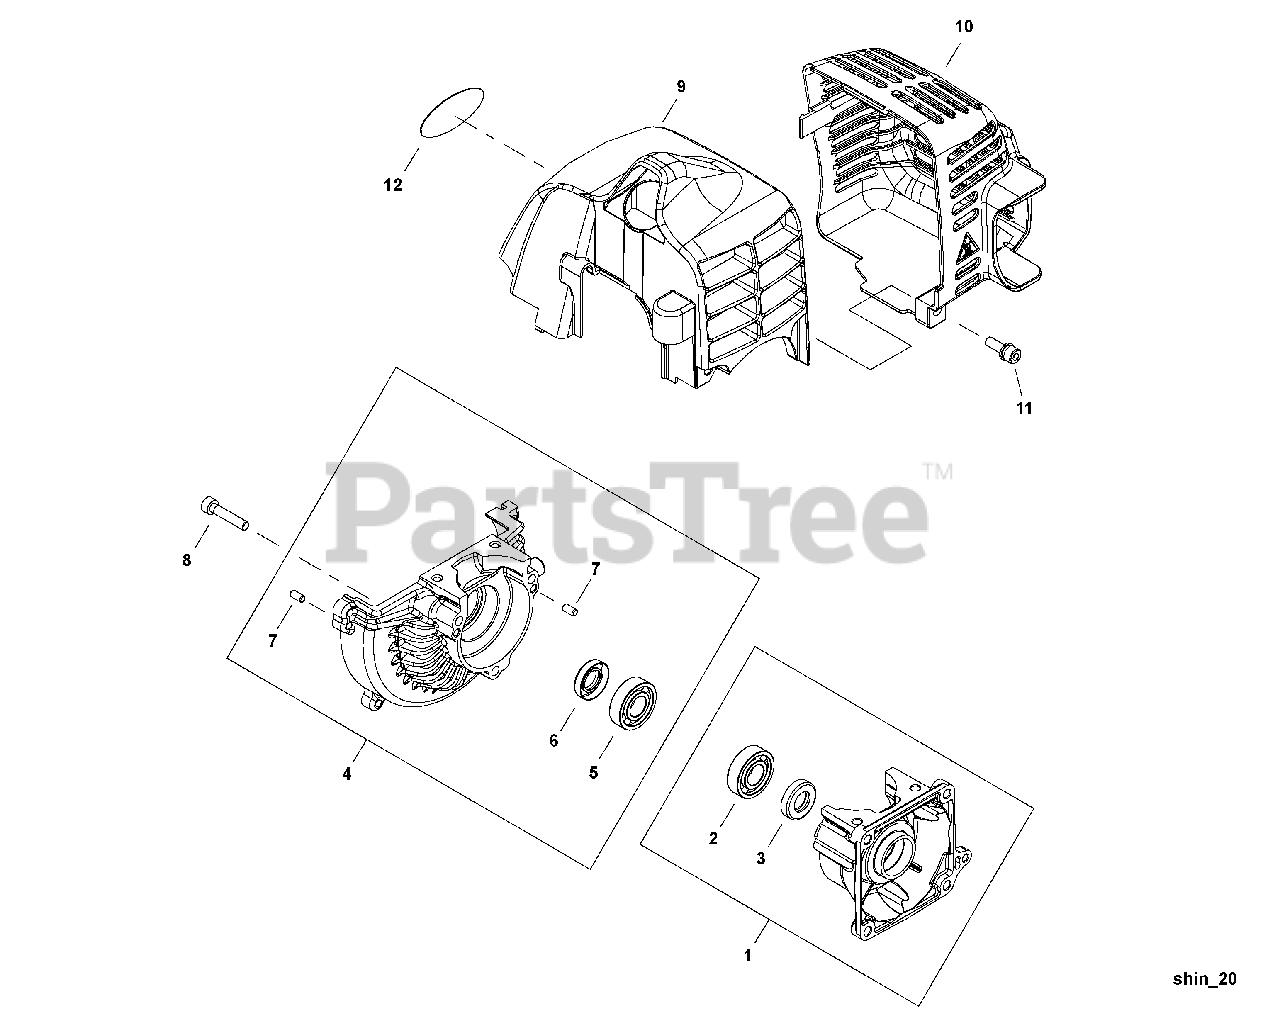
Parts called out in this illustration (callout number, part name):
1	CRANKCASE ASSY, S
2	BEARING, BALL 6201 C3
3	SEAL, OIL
4	CRANKCASE ASSY, M
5	BEARING, BALL 6201 C3
6	SEAL, OIL
7	PIN, LOCATING Ø4×8
8	BOLT 5×25
9	COVER, ENGINE
10	COVER, MUFFLER
11	BOLT, ADHESIVE M5×20
12	LABEL - MODEL 282
